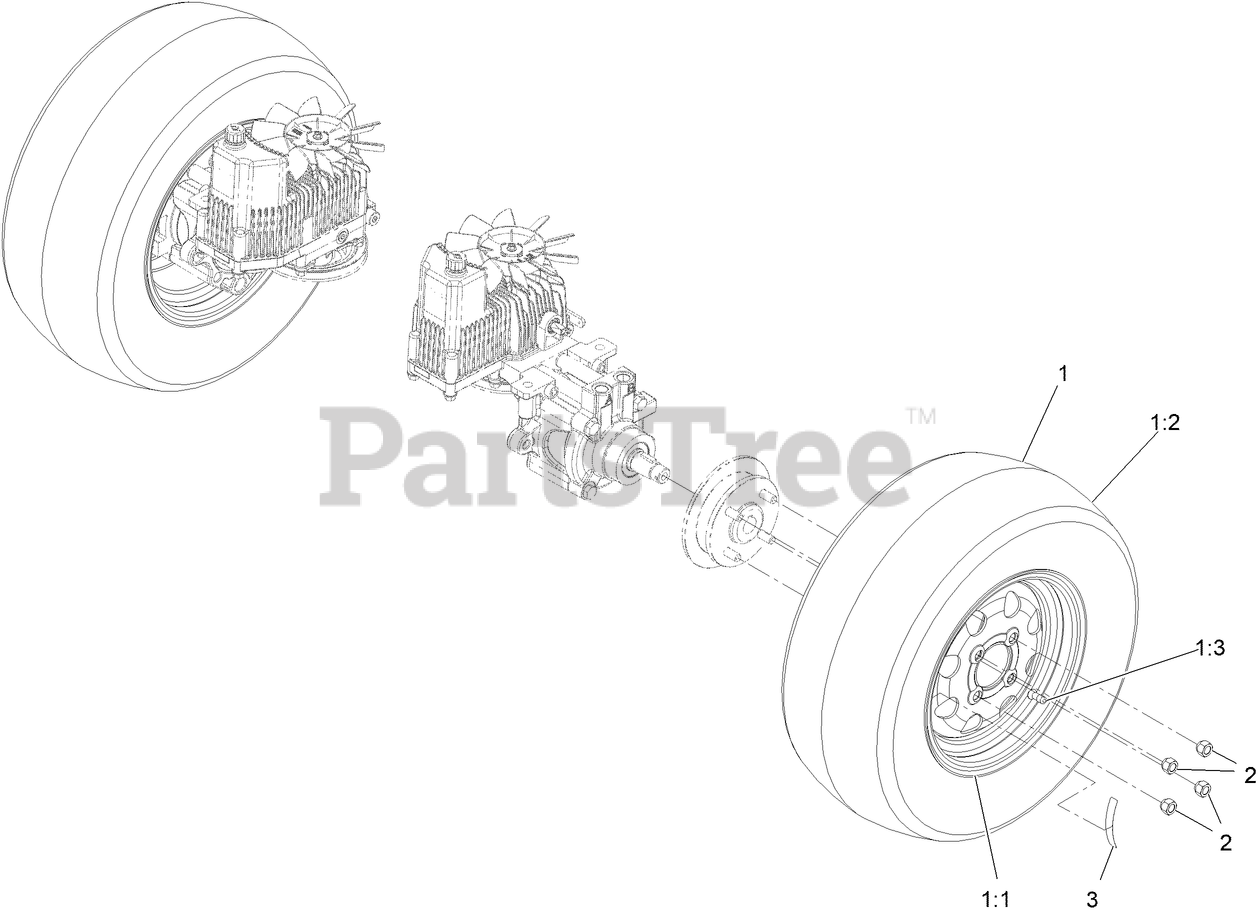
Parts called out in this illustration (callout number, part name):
1	Wheel And Tire ASM Charcoal
1:1	Rim-Charcoal
1:2	Tire-23X9.50-12
1:3	Stem-Valve
2	NUT-LUG
3	DECAL-TORQUE, WHEEL HUB LUG
